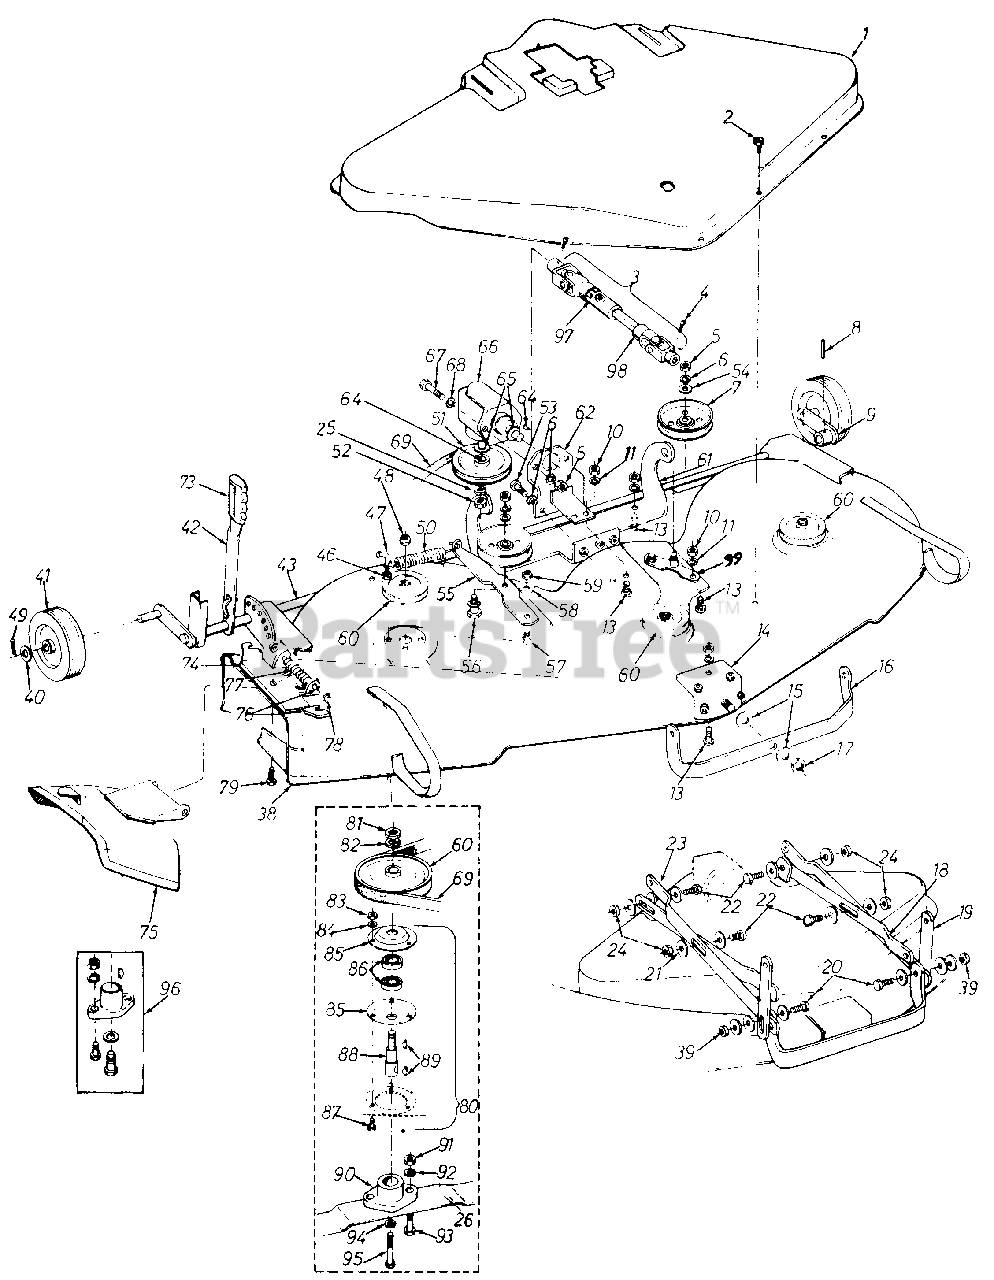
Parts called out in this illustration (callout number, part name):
1	Belt Cover
2	Hex Hd. Sheet Metal Scr. Type 3 14 x 3/8Lg.*
3	Universal Drive Shaft Comp.
4	Sq. Hd. Set Scr. 5/16-18 x 12 Cup Point*
5	Hex Nut 3/8-16 Thd.*
6	Spring L.-Wash. 3/8 I.D.*
7	Deck Idler
8	Spirol Pin 1/4 x 1-1/2 Hd.
9	Deck Wheel Bracket Ass'y.
10	Hex Nut 5/1618 Thd.*
14	Deck Hanger Bracket Ass'y.
15	Flat Washer*
16	Front Deck Hanger
17	Hex Center L.-Nut 5/8-18 Thd.
18	Inside Deck Link
19	Deck Lift Link
20	Shoulder Bolt
21	Flat Washer .531 I.D.*
22	Shoulder Bolt
23	Outside Deck Link
24	Elastic Stop Nut 3/8-16 Thd.*
25	Spring L.-Wash. 5/8 I.D.*
26	Blade 14-3/4"
38	Mower Deck Assembly
39	Hex Nut 3/8-24 Thd.*
40	Flat Washer 5/8" I.D.
41	Deck Wheel Assembly
42	Wheel Adj. Handle Ass'y.
43	Wheel Bracket Shaft Ass'y.
46	Hex Nut 1/4-20 Thd.*
47	Hook Bolt
48	Hex Jam Nut5/8-11 Thd.*
49	Cotter Pin 5/32" Dia. x 1.0" Lg.*
50	Extension Spring
51	Deck Drive Pulley
52	Hex Center L.-Nut 5/8-18 Thd .
53	Hex Bolt 3/8-16 x 1-1/4 Lg.*
54	Flat Washer 3/8 I.D.*
57	Shoulder Bolt
58	Flat Washer
59	Elastic 3/8-16 Thd.*
60	Deck Pulley
61	Deck Mtg. Brkt. Ass'y.
62	Gear Box Mtg. Ass'y.
64	Key Hi Pro
65	FlatWasher 29/32" I.D.*
66	Right Angle Gear Box
67	Hex Bolt 3/8-16 x 1-1/4 Lg.*
68	External L.-Wash. 3/8 I.D.*
69	Drive Belt Sect. "A" 105" Lg.
73	Grip
74	Adapter Assembly
75	Chute Cover Assembly
76	Hinge Pin
77	Tension Spring
78	Pushnut
79	Finger Assembly
80	Spindle Ass'y.-Sealed Bearings
81	Hex Jam Nut 5/8-11 Thd.*
82	L.-Wash. 5/8 I.D.*
83	Hex Nut 5/16-18 Thd.*
84	L.-Wash.5/16 I.D.*
85	Bearing Housing
86	Ball Bearing
87	Hex Bolt 5/16-18 x 1 Lg.*
88	Blade Spindle
89	Hi Pro Key HP-505
90	Blade Adapter
91	Hex Nut 5/16-24 Thd.*
92	L.-Wash. 5/16 I.D.*
93	Hex Bolt 5/16-24 x 1 Lg. [Heat Treated
94	L.-Wash. Heavy Duty 3/8 I.D.
95	Hex Bolt 3/8-24 x 1-1/2 Lg. [H.T.
96	Blade Adapter Kit
97	Universal Drive Shaft Female Half
98	Universal Drive Shaft Male Half
99	Idler Brkt.
